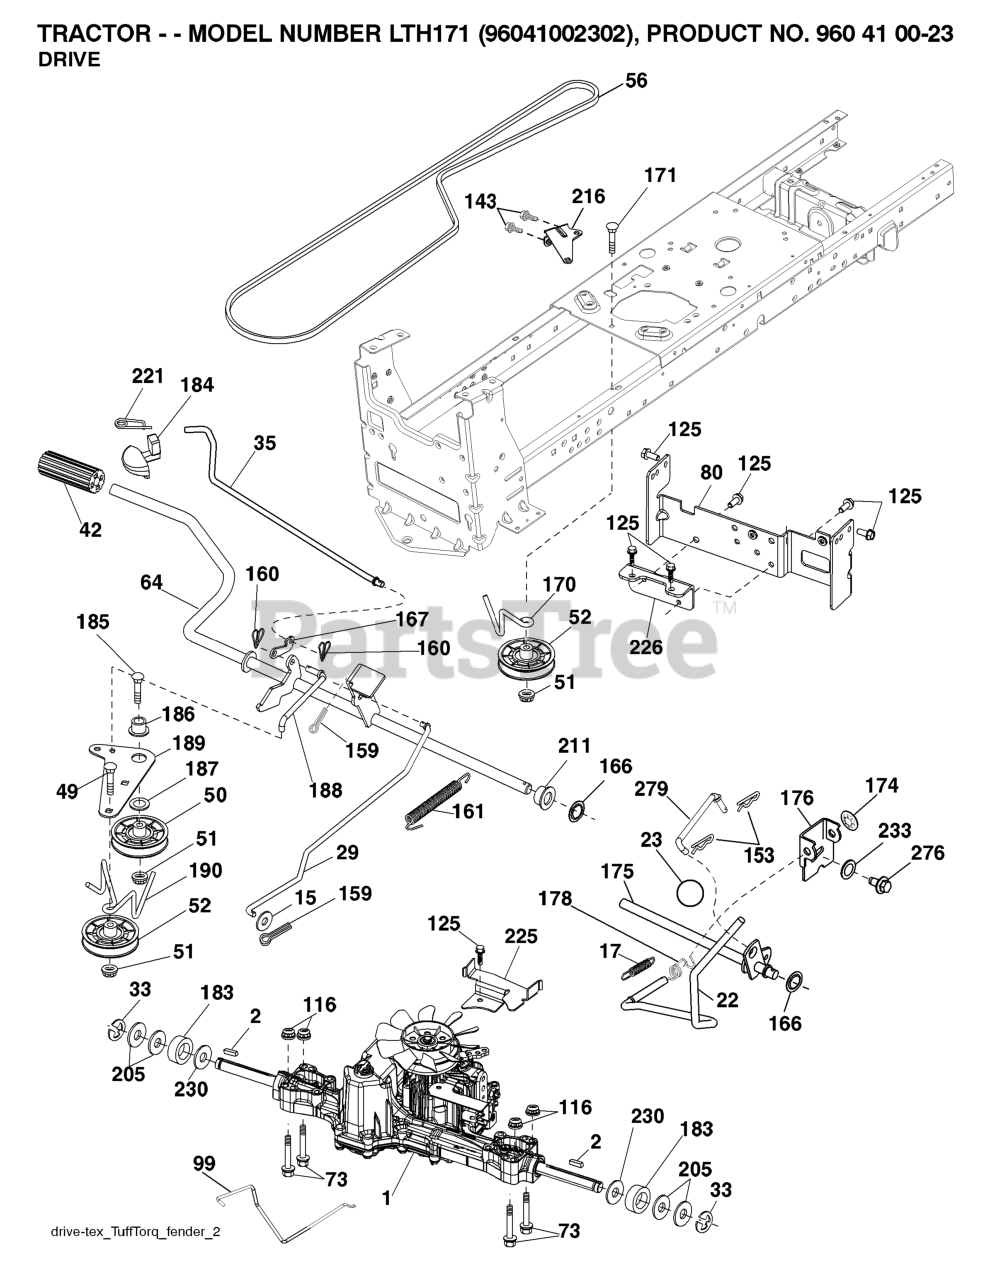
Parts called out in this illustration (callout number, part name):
2	SQUARE KEY
15	WASHER
17	SPRING.BRAKE.K46.GREEN
22	ROD.SHIFT.FENDER.TLT.2006
23	KNOB.DUCKHEAD.1/2
29	ROD.BRAKE.K46
35	ROD.CNTRL.PARK.PREDATOR.LT.TEX
42	PEDAL COVER T
50	IDLER.FLAT.910.OFFSET
51	NUT LOCK FLG 3/8-16 UNC
52	IDLER.V-GROOVE.910.OFFSET
56	V-BELT.MOWER.92.40.42/K46
64	SHAFT.ASM.PEDAL.BRAKE.
73	BOLT HEX 5/16-18 GR 5
80	STRAP TORQUE
99	ROD ASM BYPASS
116	NUT LOCK HEX FLANGE 5/16-18
125	SCREW
143	Screw 5/16-18 x 1/2 Hex, Self Tapping 5/16-18 x 1/2
153	RETAINER M
159	COTTER PIN
160	RETAINER CLIP
161	SPRING.RETURN.CLUTCH.2006
166	NUT.PUSH.625.2006
167	LATCH.BRAKE.SPRING
170	KEEPER.V-IDLER.CENTER.
174	NUT.PUSH.500.2006
175	SHAFT ASM SHIFT
176	ARM.CLEVIS.ROD.SHIFT
178	SPRING.SHIFT.GT2006
183	SPACER AXLE
184	HANDLE PARKING BRAKE
186	SPACER.RETAINER
187	WASHER 12/32X2X10GA
188	RP.LINK.CLUTCH.GROUND.DRIVE
189	BELLCRANK.GROUND.DRIVE.TEX.
190	KEEPER.BELLCRANK.DRIVE
211	BUSHING.SHAFT.BRAKE.HAND
216	BRACKET.PULLEY.IDLER.W/TEX
221	RETAINER.SPRING.CLIP.H
225	KEEPER.BELT.TRANSAXLE.K46
226	BRACKET.MOUNT.TORQUE.K46.TLT
230	WASHER.HARDENED
233	WASHER SERRATED
276	BOLT FIN HEX 7/16-14 X 1
279	LINK.SHIFT.T/A.K46.FEND.TX
